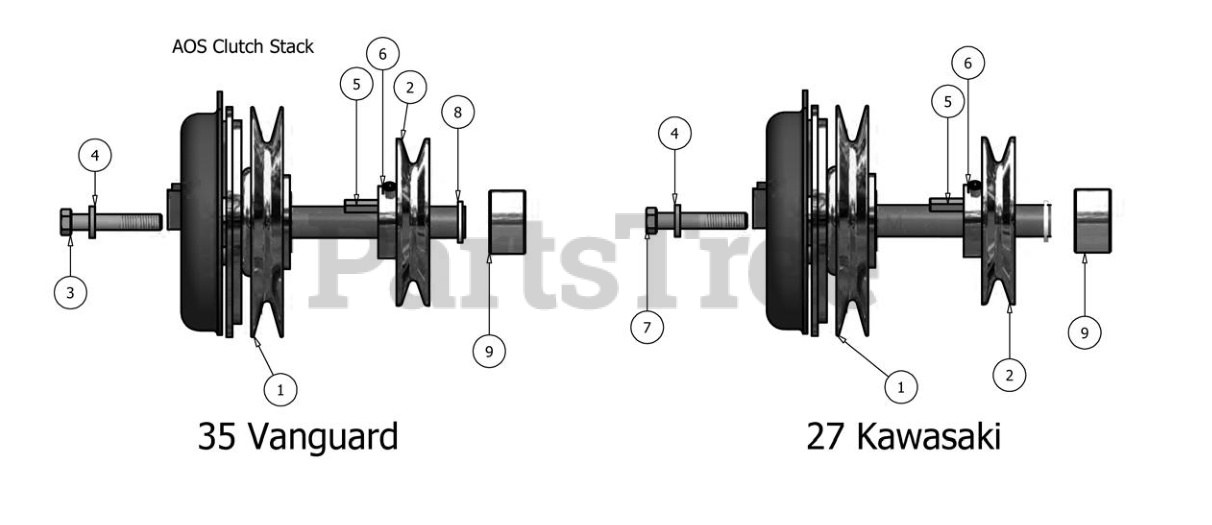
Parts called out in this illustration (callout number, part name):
1	Clutch Assembly
2	4 3/4" Motor Pulley
3	7/16" x 2 1/2"Fine Thread Bolt
4	7/16" Lock Washer
5	1/4" x 1" Key
6	3/8" Set Screw
7	10mm x 552 Bolt
8	1 1/8" Flat Spacer
9	1 1/8 collar spacer
